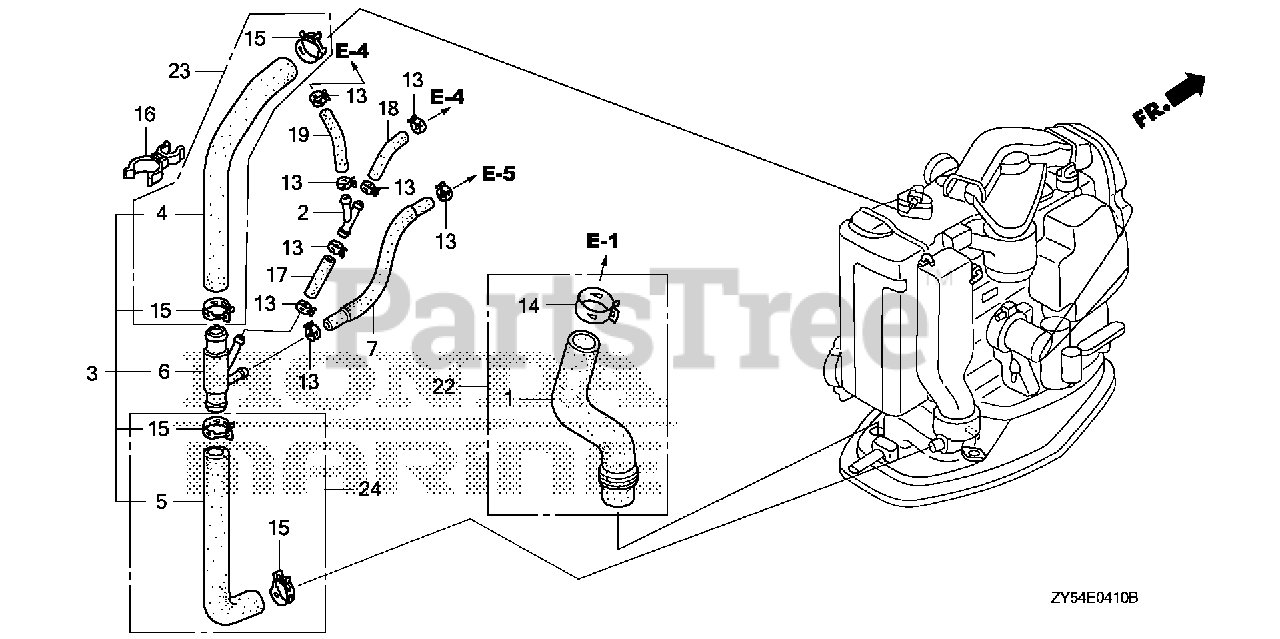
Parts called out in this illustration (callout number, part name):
1	TUBE, OIL
2	JOINT, FUEL TUBE
3	TUBE, WATER RELIEF
4	TUBE A, WATER RELIEF
5	TUBE B, WATER RELIEF
6	JOINT, FOUR-WAY
7	TUBE E, WATER
13	CLAMP, TUBE (D10.5)
14	CLAMP, TUBE (D32.5)
15	CLAMP, TUBE (D25.0)
16	CLAMP, WATER TUBE
17	BULK HOSE, VACUUM (7X3000) (7X75)
18	BULK HOSE, VACUUM (7X3000) (7X90)
19	BULK HOSE, VACUUM (7X3000) (7X120)
22	TUBE SET, OIL
23	TUBE SET A, WATER RELIEF
24	TUBE SET B, WATER RELIEF
